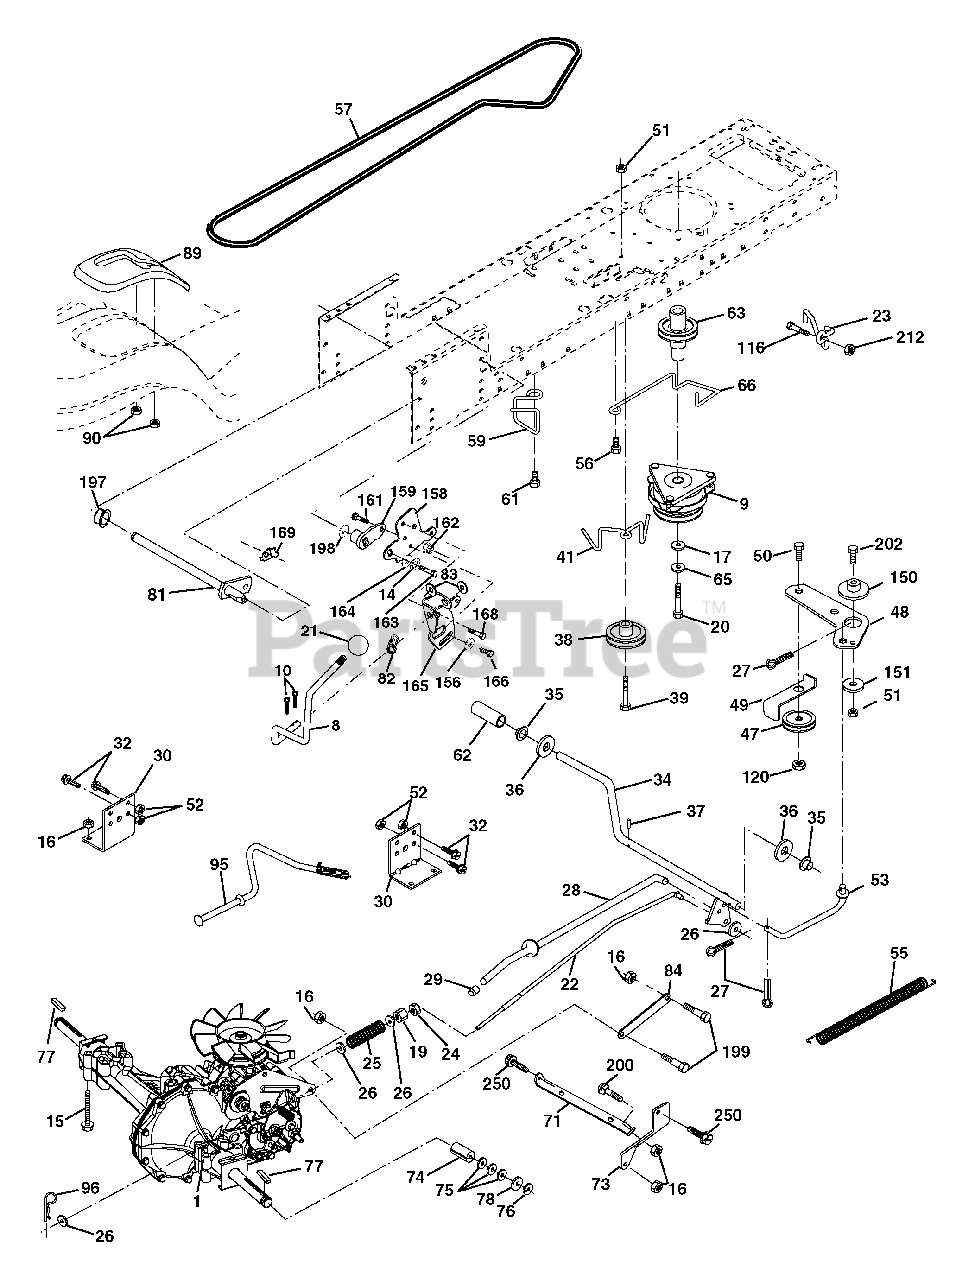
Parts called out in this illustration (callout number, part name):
8	Rod Shift Fender Adjust STLT
9	Clutch
10	Pin Cotter 1/8 x 1 CAD
14	Washer Lock Hvy Helical
15	Bolt Hex 5/16-18 Unc Flghd
16	Nut Lock Hex W/Ins. 5/16-18 Unc P
17	Washer 1-1/2 x 15/32 x .250
19	Nut Lock Hex W/Ins 3/8-16 Unc
20	Bolt Hex 7/16-20 x 4 x Gr.5-1.5
21	Knob Deluxe 1/2-13 UNC BLK/BLK
22	Rod, Brake Hydro
23	Bracket Asm Anti-Rot
24	Nut Hex Jam 3/8-16 UNC
25	Spring, Brake Rod
26	Washer
27	Pin Cotter 1/8 x 3/4 CAD.
28	Rod, Parking Brake
29	Cap,Parking Brake
30	Bracket, Transaxle
32	Bolt Hex Hd 5/16-18 Unc x 3/4
34	Shaft, Foot Pedal
35	Bearing, Nylon
37	Pin, Roll
38	Pulley, Composite, Flat
39	Bolt, Fin, Hex 3/8-16 x 3
41	Keeper, Belt Idler
47	Pulley, Idler, V-Groove Plastic
48	Bellcrank Clutch Grnd Drv STL
49	Retainer, Belt Style Spring
50	Bolt 3/8-16 x 1-1/2 Gr. 5
52	Nut Crown Lock 5/16-18
53	Link, Clutch
55	Spring, Return, Clutch
56	Screw 3/8-16 x 1.0
57	V-Belt, Ground Drive
59	Keeper, Center Span
61	Screw 3/8-16 x .875
62	Cover, Pedal
63	Pulley, Engine
65	Washer Lock Hvy HLCL Spr 7/16
66	Keeper Belt Engine
71	Strap Torque Lh Hydro
73	Strap Torque Rh Hydro
74	Spacer, Axle
75	Washer 25/32 x 1-1/4 x 16 Ga.
77	Key, Square
78	Washer 25/32 x 1-5/8 x 16 Ga
81	Shaft Asm Cross Tapered
82	Spring Torsion T/A
83	Washer 17/32 x 3/4 x 16 Ga.
84	Link Transaxle
89	Console, Shift
90	Nut Self Thd 1/4
95	Control Asm. Bypass Hydro
96	Retainer Spring 1 Zinc/Cad
116	Bolt 3/8-16 x 1
120	Nut Lock Flg 3/8-16
150	Spacer Retainer
151	Washer 13/32 x 2 x 10 Ga.
156	Washer Srrted 5/16ID x 1.125
158	Bracket Shift Mount
159	Hub Shift
161	Bolt Rdhd Sqnk 1/4-20 x 3/4 Gr 5
162	Nut Crownlock 1/4-20 Unc
163	Bolt Hex Fin 1/4-20 Unc x 1 Gr 5
164	Washer 5/8 x .281 x 10 Ga
165	Bracket Pivot Lever
166	Screw 5/16-18 x 5/8
168	Bolt Shoulder 5/16-18 x .561
169	Plate Fastening STLT/CRD
197	Nyliner Snap 5/8 ID
198	Washer Nyl 7/8 ID x .105 Hyd
199	Bolt Shoulder 5/16-18 Unc
200	Bolt Rdhd Sqnk 5/16-18 Unc x 1
202	Bolt Rd Hd 3/8-16 Unc x 1-3/4 Gr. 5
212	Nut Hexlange Lock
250	Screw 3/8-16 x .75
